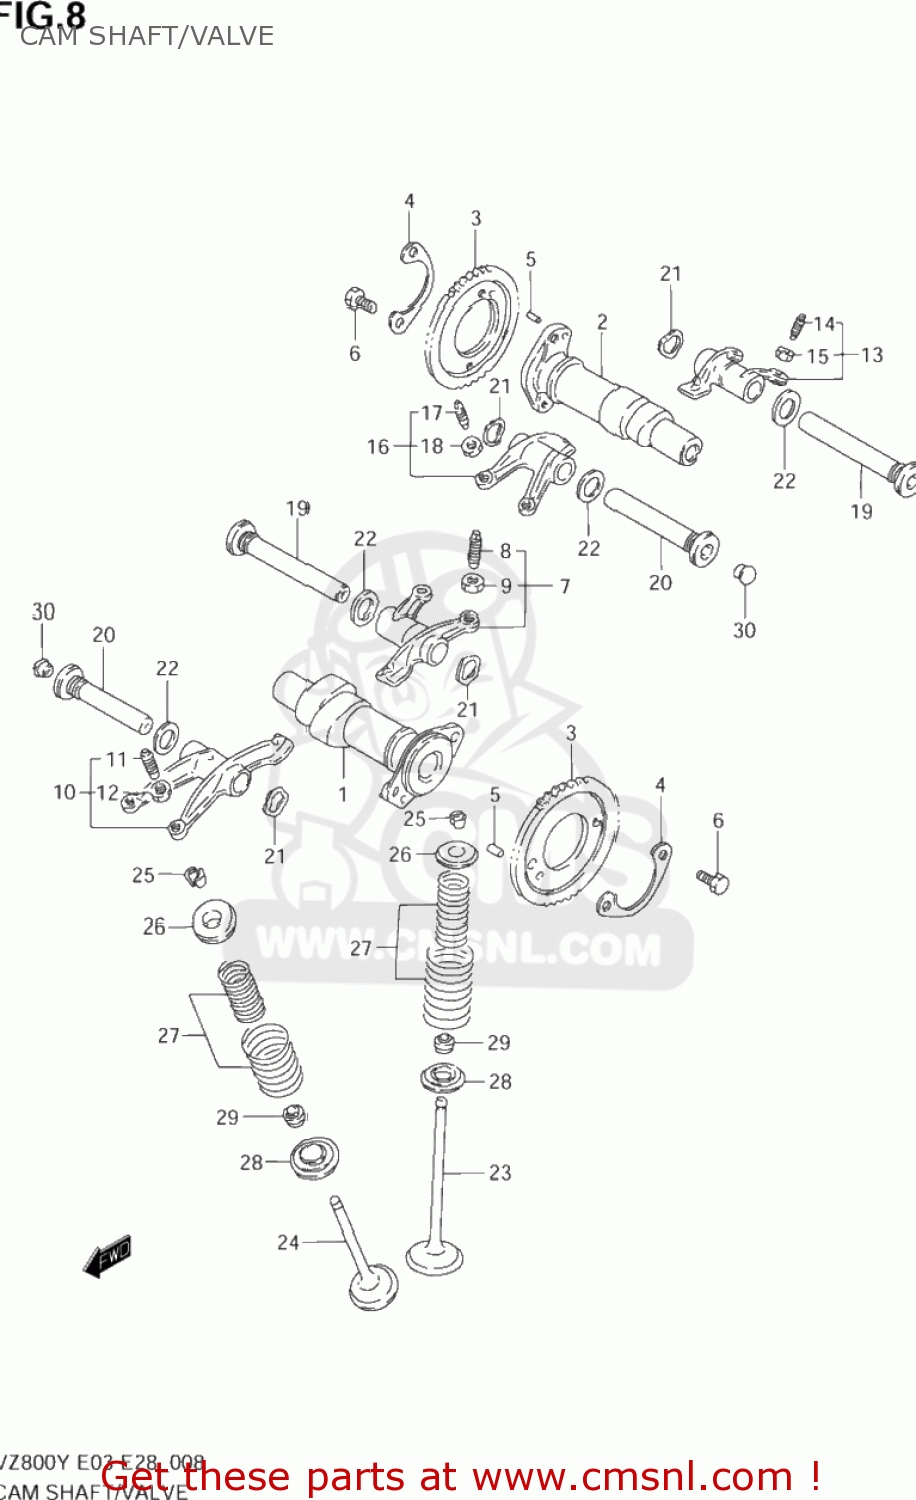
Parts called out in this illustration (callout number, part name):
1	CAMSHAFT,FR
2	CAMSHAFT,RR
3	SPROCKET,CAMSHAFT(NT:42)
4	WASHER,CAM CHAIN SPROCKET
5	PIN
6	BOLT(6X12.5)
7	ARM COMP,INTAKE VALVE ROCKER
8	SCREW,TAPPET ADJUSTING
9	NUT,ADJUSTING SCREW
10	ARM,EXHAUST VALVE ROCKER FR
11	SCREW,TAPPET ADJUSTING
12	NUT,ADJUSTING SCREW
13	ARM,INTAKE VALVE ROCKER RR
14	SCREW,TAPPET ADJUSTING
15	NUT,ADJUSTING SCREW
16	ARM,EXHAUST VALVE ROCKER RR
17	SCREW,TAPPET ADJUSTING
18	NUT,ADJUSTING SCREW
19	SHAFT,INTAKE VALVE ROCKER ARM
20	SHAFT,EXHAUST VALVE ROCKER ARM
21	WASHER
22	GASKET(13.8X18.8X4.8) (NAS)
23	VALVE,INTAKE
24	VALVE,EXHAUST
25	COTTER,VALVE
26	RETAINER,VALVE SPRING
27	SPRING SET,VALVE
28	SEAT,VALVE SPRING
29	SEAL,OIL(5.5X11X8.2)
30	CAP(OD:10)
